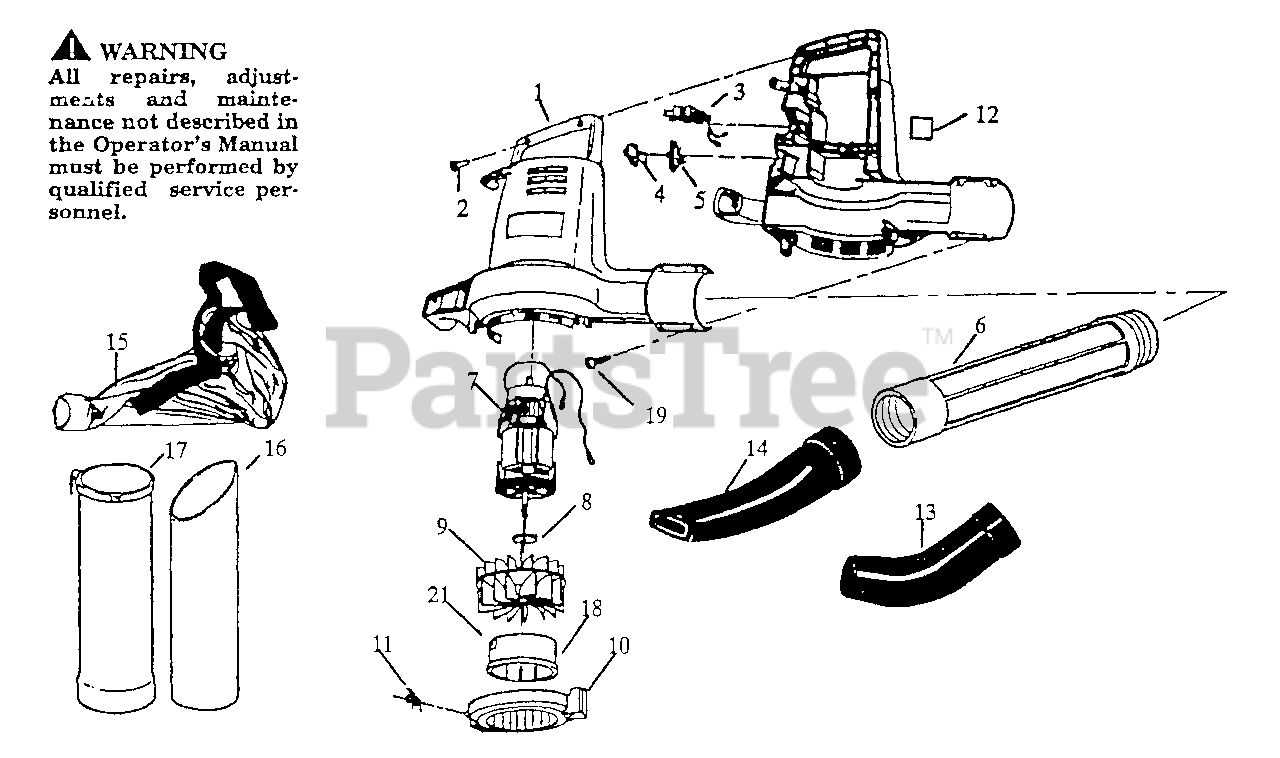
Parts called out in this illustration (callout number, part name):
1	Housing Set
3	Wire Harness
4	Switch Cover
6	Blower Tube
7	Motor Ass'y
10	Inlet Cover
13	Concentrator Nozzle
14	Nozzle
15	Vacuum Bag Kit
16	Vacuum Tube (Lower)
17	Inlet Tube
18	Restrictor-Inlet
19	Screw-Housing
